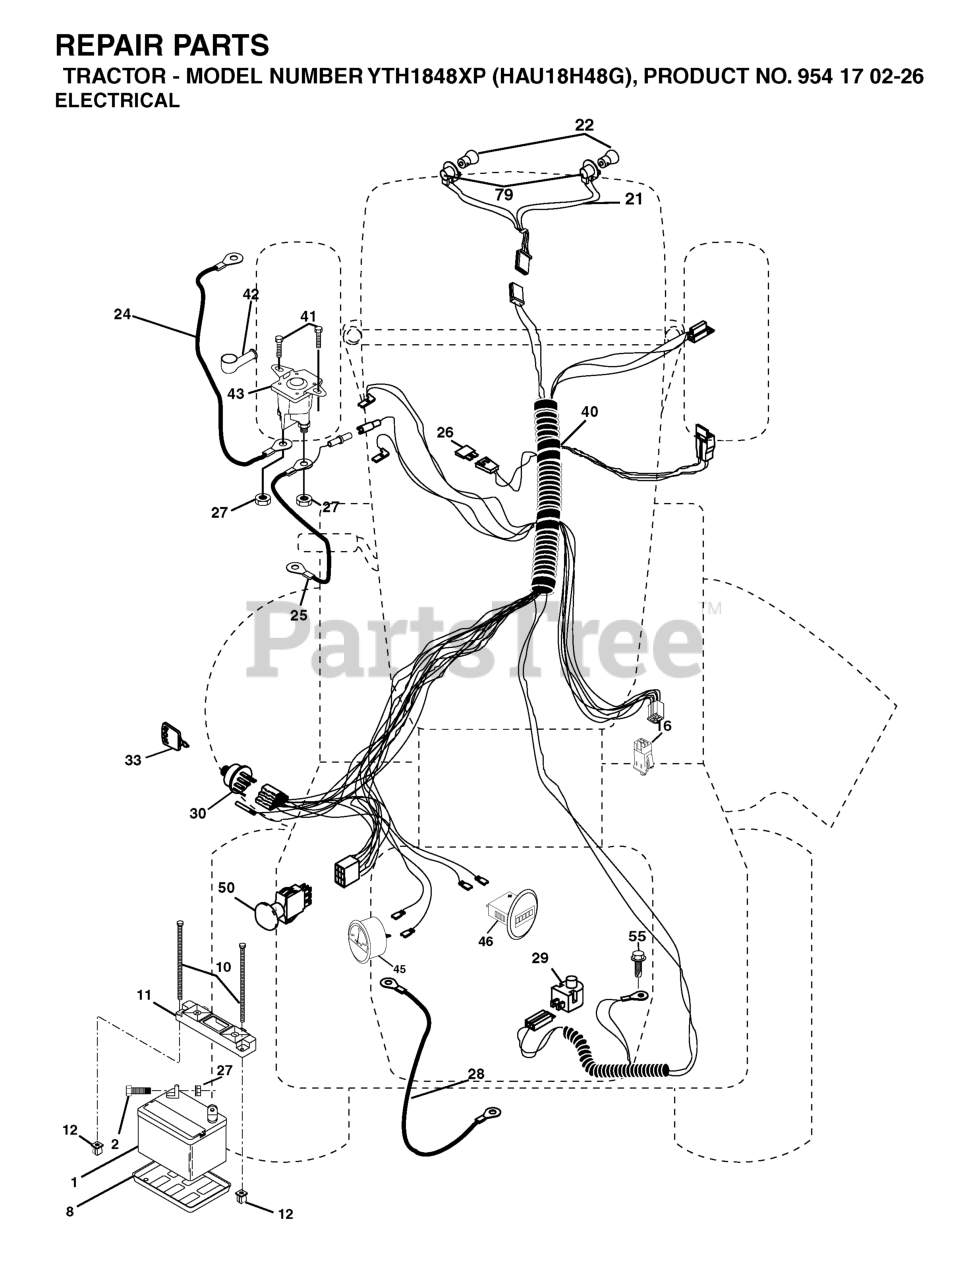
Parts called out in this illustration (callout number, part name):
1	BATTERY 12V .35 AMP
2	BOLT.HEX.1/4.X.3/4.DICHROMATE
8	BATTERY TRAY T
10	BOLT 1/4-20 X 7.5
11	BATTERY HOLDDOWN FRONT MOUNT
12	NUT, PUSH NYLON 1/4" BATTERY
16	SWITCH INTERLOOK PUSH-IN
21	HARNESS.W/LIGHT SOCKET
25	CABLE BATTERY 6 GA 22" W/16W
26	FUSE 20AMP
27	NUT
28	CABLE GROUND 6 GA 21" 90T BLK
29	RP.SWITCH.PLUNGER.NC.GRAY
30	IGNITION SWITCH
33	KEY MLD GEN DELTA
41	SCREW
42	TERMINAL COVER
43	SOLENOID
45	RP AMMETER.ROUND.SILVER.DELTA
46	RP HOURMETER SNAP-IN
50	RP.PTO.SWITCH.8 TERMINAL.BLACK
55	Screw 5/16-18 x 1/2 Hex, Self Tapping 5/16-18 x 1/2
79	BULB HOLDER ASM.
